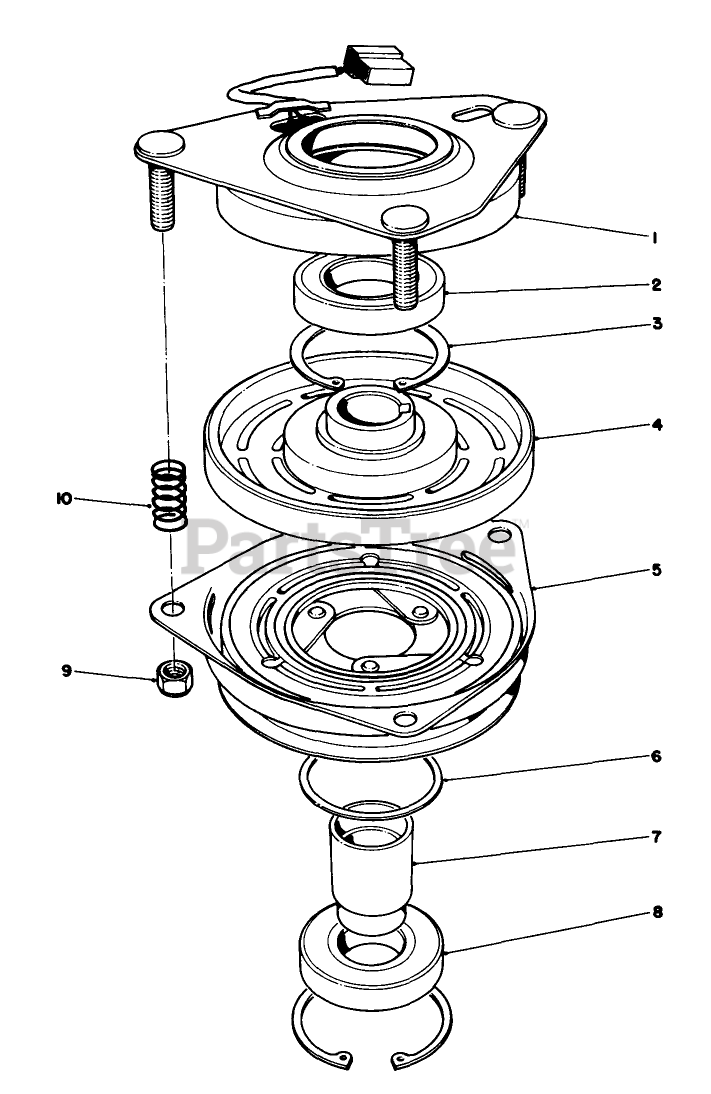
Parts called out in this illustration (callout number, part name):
1	FIELD BEARING ASM
2	BEARING-FIELD
3	RING-RETAINING
4	FIELD COIL/ROTOR BEARING ASM
6	SPACER-BEARING, PULLEY
7	COLLAR-BEARING
9	NUT-LOCK
10	SPRING
